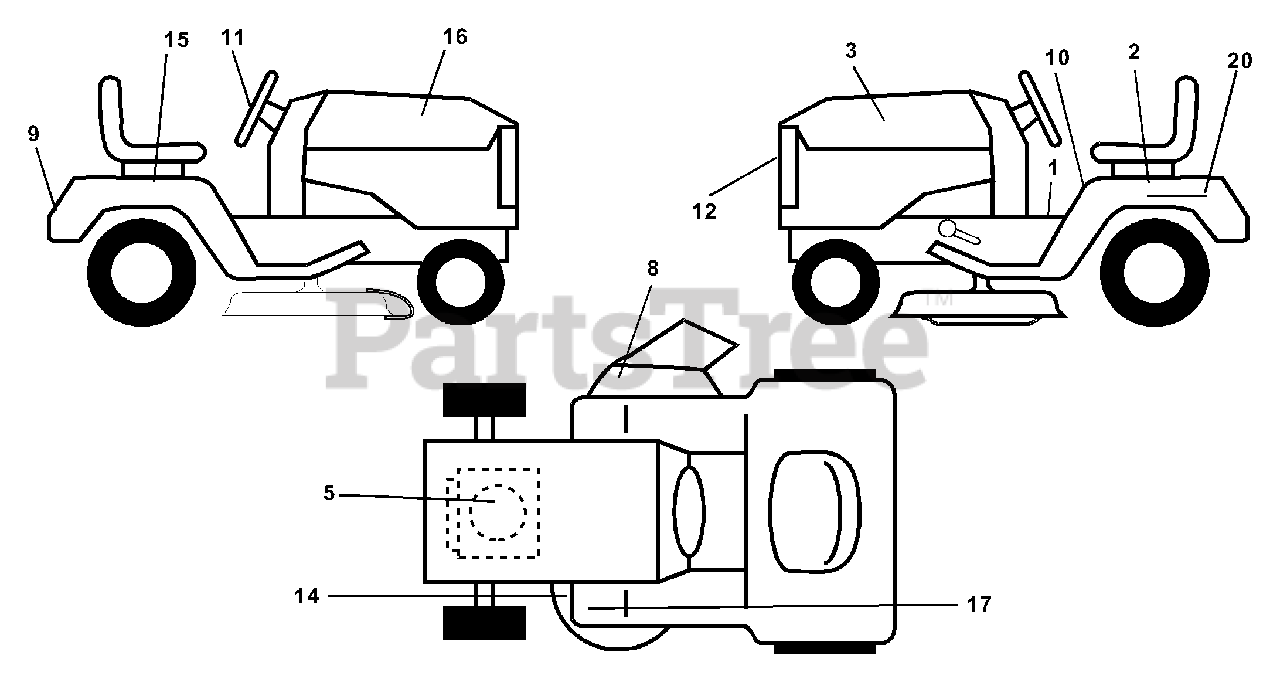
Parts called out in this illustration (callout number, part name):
1	Decal Oper
2	Decal Fender Auto
3	Decal Hood LH
5	Decal HP Engine
8	Decal Warning Mult-Language
9	Decal Fender Logo
10	Decal Fender Danger E/F
11	Decal Ins Strg Whl
12	Decal Grille
14	Decal V-Belt Schematic
15	Decal Fender Auto Rh
16	Decal Hood Rh
17	Decal Clutch/Brake
20	Decal Bat Dan/Psn
20	Decal By Pass Lt Hydro
